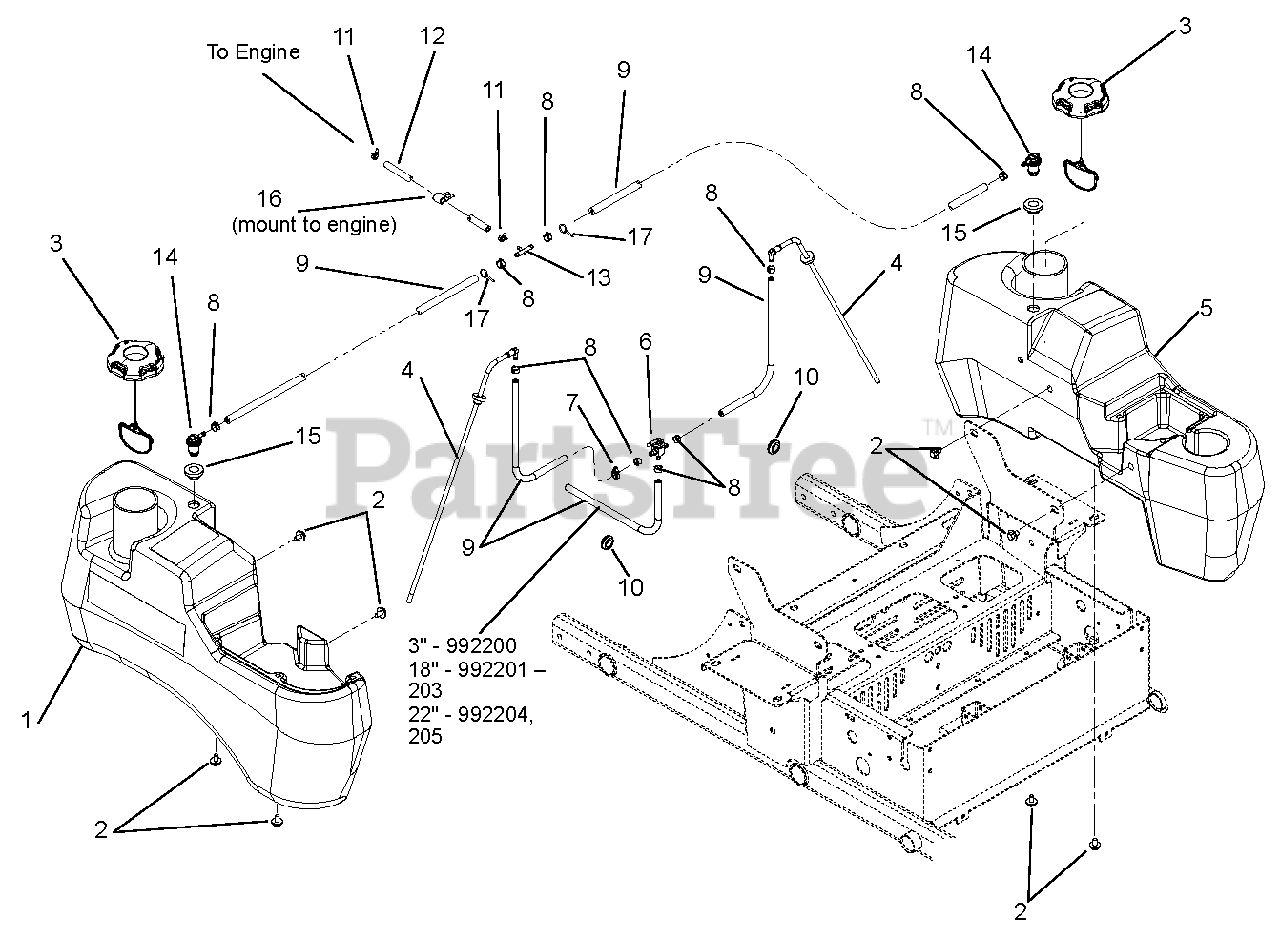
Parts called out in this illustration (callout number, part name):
1	Tank, Right Hand Fuel
2	Bolt, SEMS .31-18 x .62
3	Cap, Fuel, EPA
4	Assembly, Large Tank Fuel Pick-Up
5	Tank, Left Hand Fuel
6	Valve, Fuel
7	Routing Clip (1/2" ID)
8	Clamp, Fuel Line
9	Hose, .25 Low-Perm Bulk Gas
10	Grommet, Rubber 5/8 ID/1.13 OD
11	Clamp, Hose, Spring .188
12	Hose, .188 Low-Perm Bulk Gas
13	Tee, 1/4HS Run x 3/16HS Branch
14	Valve, Combination
15	Grommet, Remote Vent Nitrile
17	Cable Tie with Tree (.25 hole)
